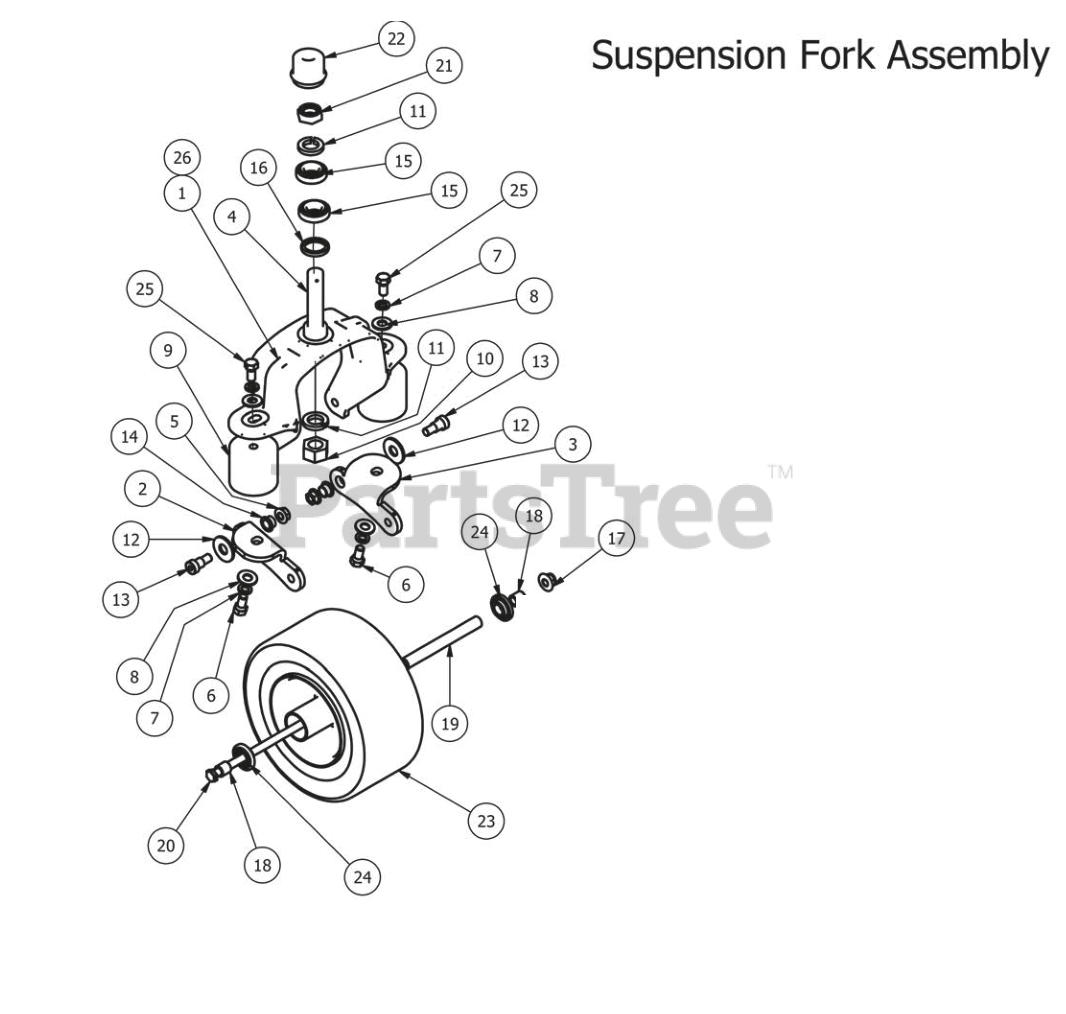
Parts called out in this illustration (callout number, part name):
1	Suspension Fork Top/Side Combo
2	Suspension Fork - Bottom Left
3	Suspension Fork - Bottom Right
4	Front Suspension Fork Spindle
5	1/2" Flange Nut
6	1/2" x 1" Hex Bolt
7	1/2" Lock Washer
8	1/2" Washer (Grade 8)
9	Vibration Mount- Red Dot
10	1" Fine Thread Nut
11	1" Lock Washer
12	5/8" Flat Washer
13	5/8" x 5/8" Shoulder Bolt
14	Bronze Bushing - SF-2024-8
17	1/2-13 Nylon Flange Nut-Orange
18	3/4 OD x 1/2 ID x 3\4 Length
19	Front Wheel Spanner
20	1/2" x 10" Bolt
21	1" Fine Thread 1/2 Nut
22	Dust Cover
23	Tire and wheel assembly
24	1-3/4" Bearing Large Bore Front Rim
25	1/2-13 x 1-1/4 Hex Bolt
26	Suspension Fork Assembly
